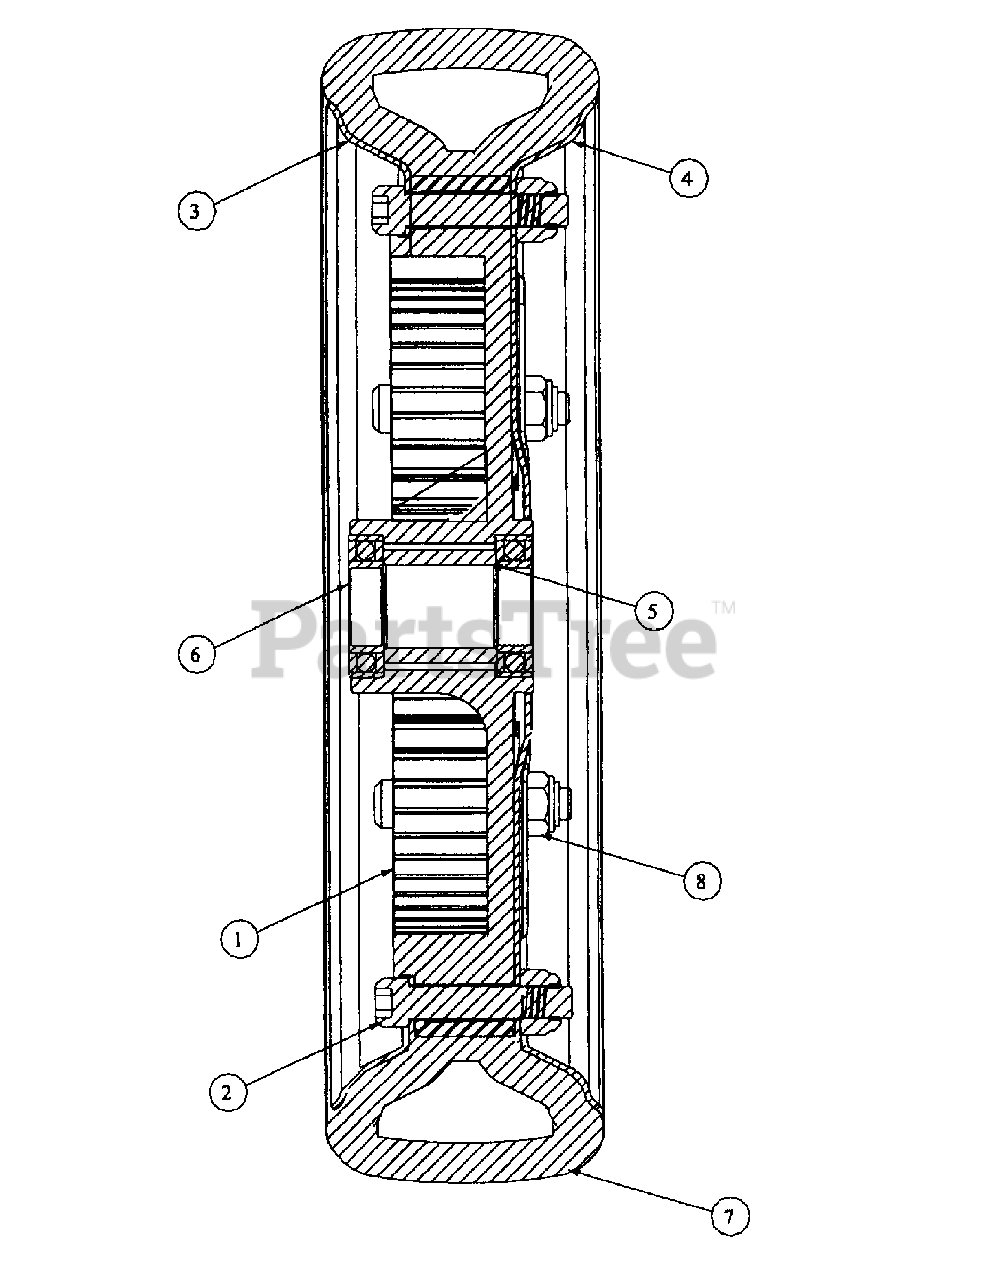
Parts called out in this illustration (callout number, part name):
1	internal Gear, 63T w/ Hub
2	Socket Screw, 1/4-20 x 1.25
3	Rim Wheel, Inner Half
4	Outer Half, Wheel Rim
5	Spacer, .635 ID x .86 Long
6	Ball Bearing, 15mm x 28mm x 7mm
7	Tire, 9 x 2.125
8	Hex, Lock Nut, 1/4-20
